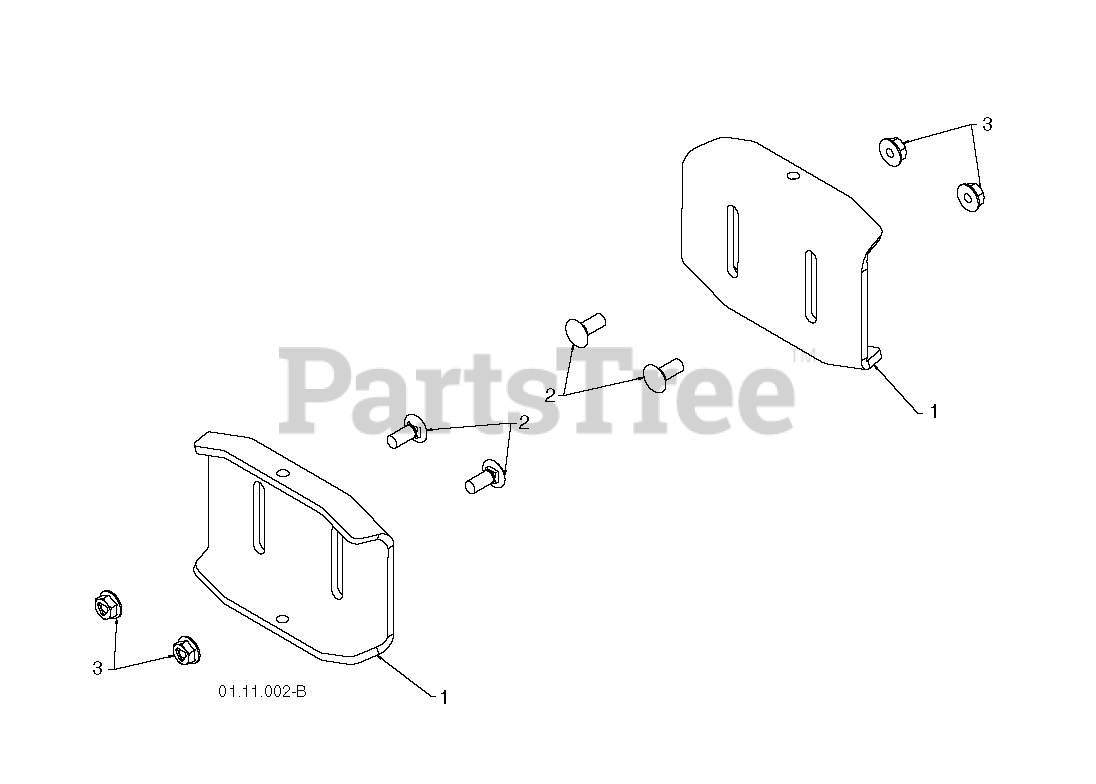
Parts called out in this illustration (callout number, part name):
1	SKID PLATE
2	BOLT
3	NUTNYLOK.FLRANGE.5/16-18
